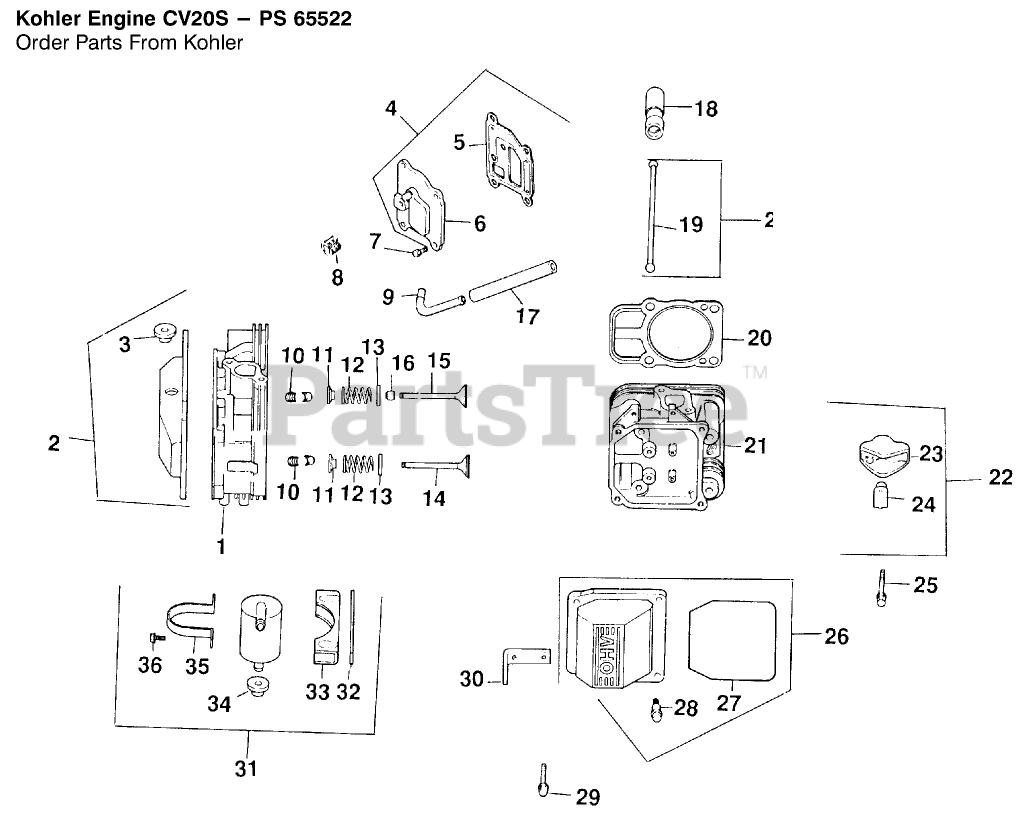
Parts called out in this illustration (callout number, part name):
1	#1 Cyl. Head Asm
2	Kit-Valve Cover/Breather (Incl. Ref.# 3 & 27-28)
3	Grommet-Rubber
4	Kit-Breather Cover Gasket (Incl. Ref.#5-6)
5	Gasket-Breather
6	Cover-Breather
7	Screw
8	Plug
9	Fitting
10	Retainer Kit
11	Cap-Spring, Valve
12	Spring-Valve
13	Retainer-Spring
14	Valve-Exhaust
15	Valve-Intake
16	Seal-Stem, Valve
17	Hose
18	Lifter-Valve
19	Rod-Push
20	Gasket-Cylinder Head
21	#2 Cyl. Head Asm,
22	Kit-Valve Train (Incl. Ref.#19 & 23-24)
23	Arm-Rocker
24	Pivot-Arm, Rocker
25	Screw
26	Kit-Valve Cover (Incl. Ref. # 27-28)
27	"O"Ring
28	Screw
29	Screw
30	Strap-Lifting
31	Kit-Breather Separator (Incl. Ref. # 32-36)
32	Spacer
33	Bracket
34	Grommet
35	Strap-Lifting
36	Screw
